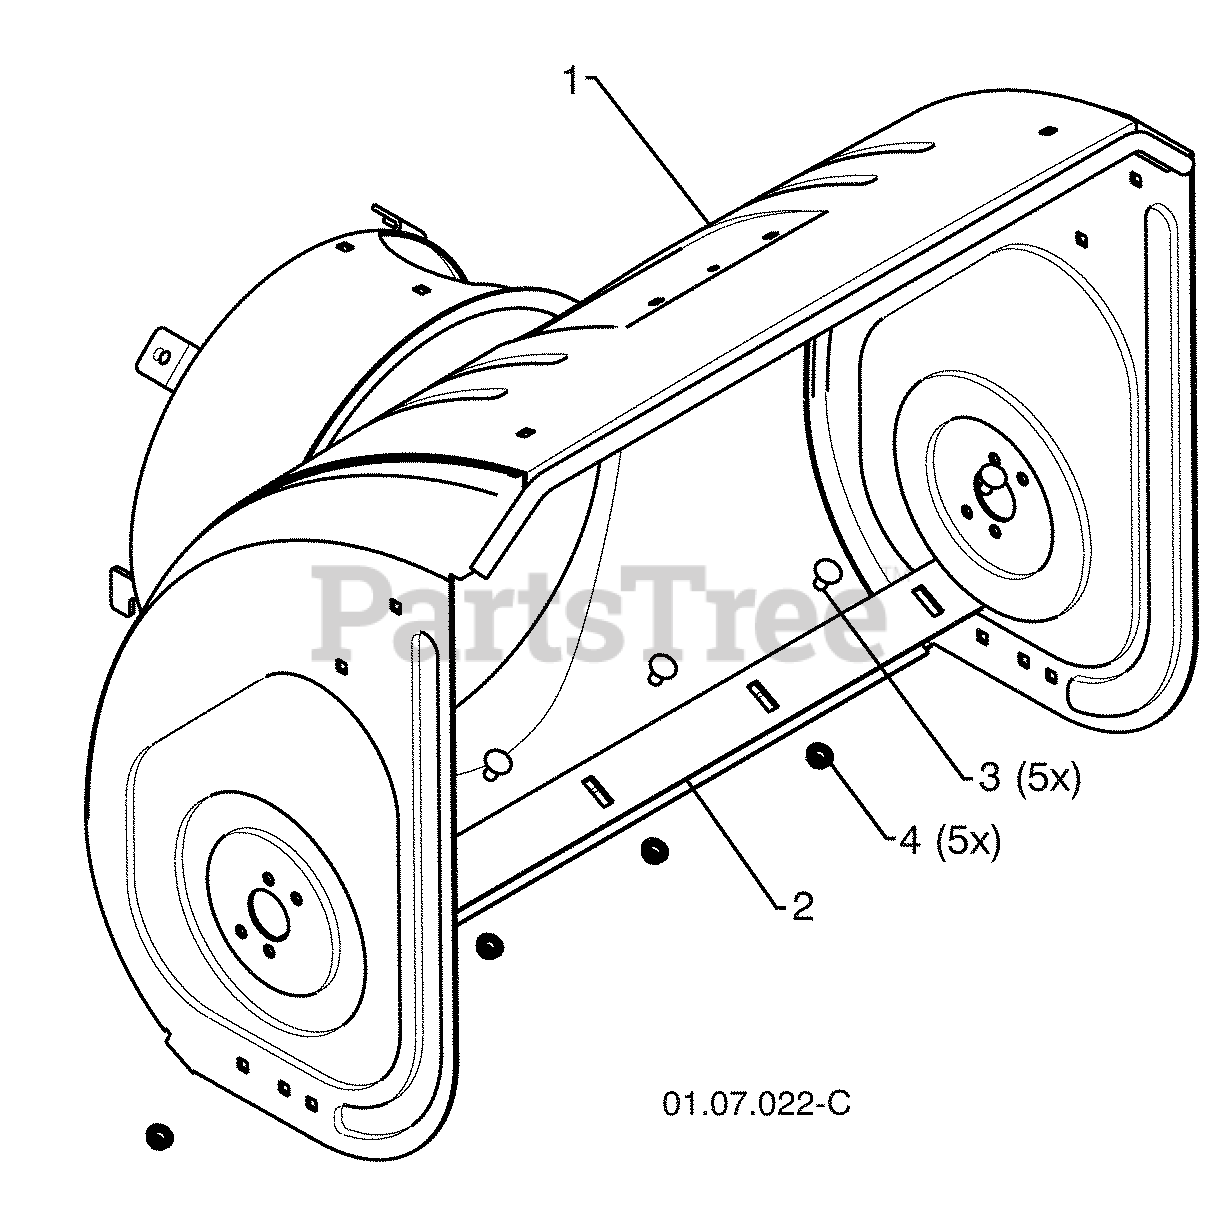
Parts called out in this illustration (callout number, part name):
1	AUGER HOUSING
2	SCRAPER BAR
3	CARRIAGE BOLT 5/16-18 X .625
4	NUT 5/16-18
